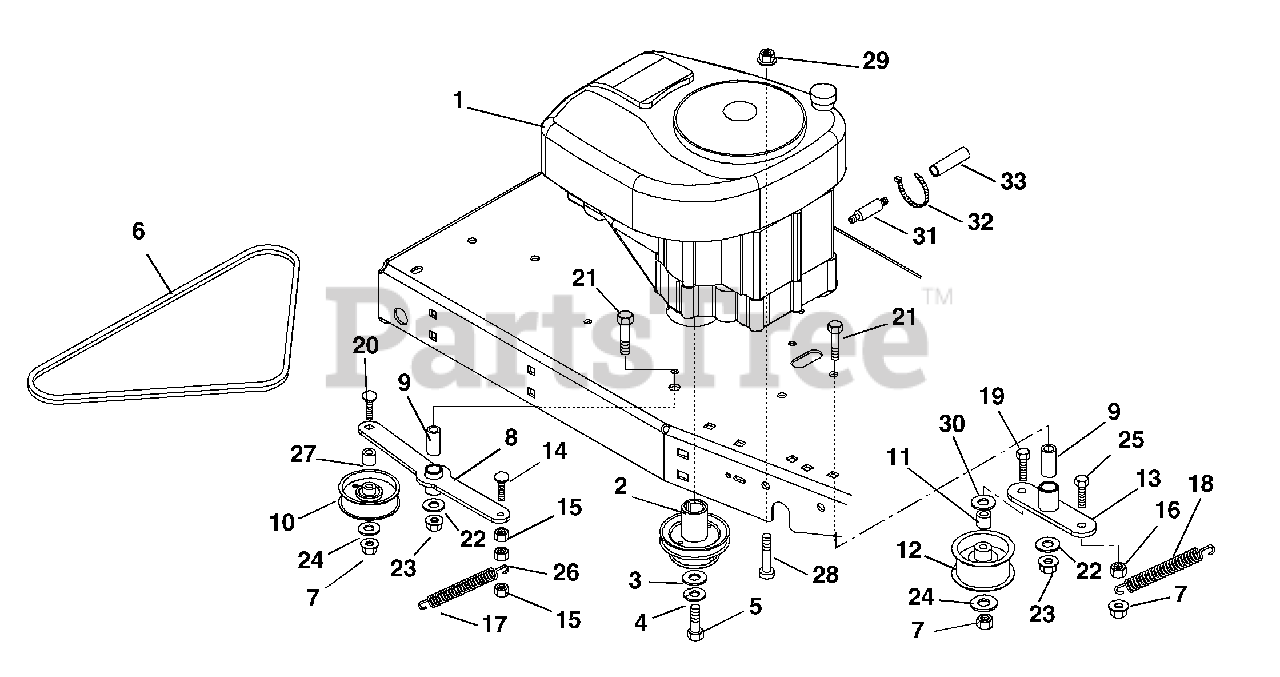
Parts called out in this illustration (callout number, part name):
1	ENGINE GROUP-12 HP
2	ENGINE-SHEAVE
3	WSHR-FL-STL.511X1.441X.125 YWZ
4	@WSHR-LK .44X.109 REG YWZC
5	BLT-HEX .44-20X1.50 GR5 YWZC
6	V-BELT, HA-RAW EDGE
7	NUT-LK-TOP-FLG .38-16 BLKZC
8	WLDM'T-IDLER (IZT)
9	BSHG-SLV .500X.750X1.560
10	IDLER-PLY FLAT 3.25 X .38 X1.0
11	BSHG-SPCR .41X75X.69
12	IDLER 2.75X1.25
13	BRKT, IDLER (WLDMNT)
14	@BLT-RDHDSQNK .31-18X1.25 G5YZ
15	NUT-LK ESNA THIN .50-13 YWZC
16	@NUT-SPNLK-FLG .375-16 YWZC
17	SG-TENS .075X.75X2.25 WLD20.7
18	SG-TENS .080X.687X5.16 WLD 28
19	@BLT-HEX .38-16X2.75 GR5 YWZC
20	@BLT-RDHDSQNK .38-16X2.00 G5YZ
21	@BLT-HEX .50-13X2.25 GR5 YWZC
22	@WSHR-FL-STL.563X1.38X.109YWZC
23	@NUT-LK-TOP-FLG .50-13 YWZC
24	@WSHR-FL-STL.438X1.00X.083 YWZ
25	@BLT-HEX .38-16X1.25 GR5 YWZC
26	@NUT-SPNLK-FLG .312-18 YWZC
27	BSHG-SLV .391X.688X.52 PM
28	SCR-SKH BTHD .31-18 X 1.50 GR8
29	@NUT-LK-TOP-FLG .31-18 YWZC
30	WSHR,FLT .438X1.00X.160 ZCC
31	VALVE, OIL DRAIN
32	CABLE TIE LG 5-1/2
33	TUBE, OIL DRAIN 8" CLEAR VINYL
